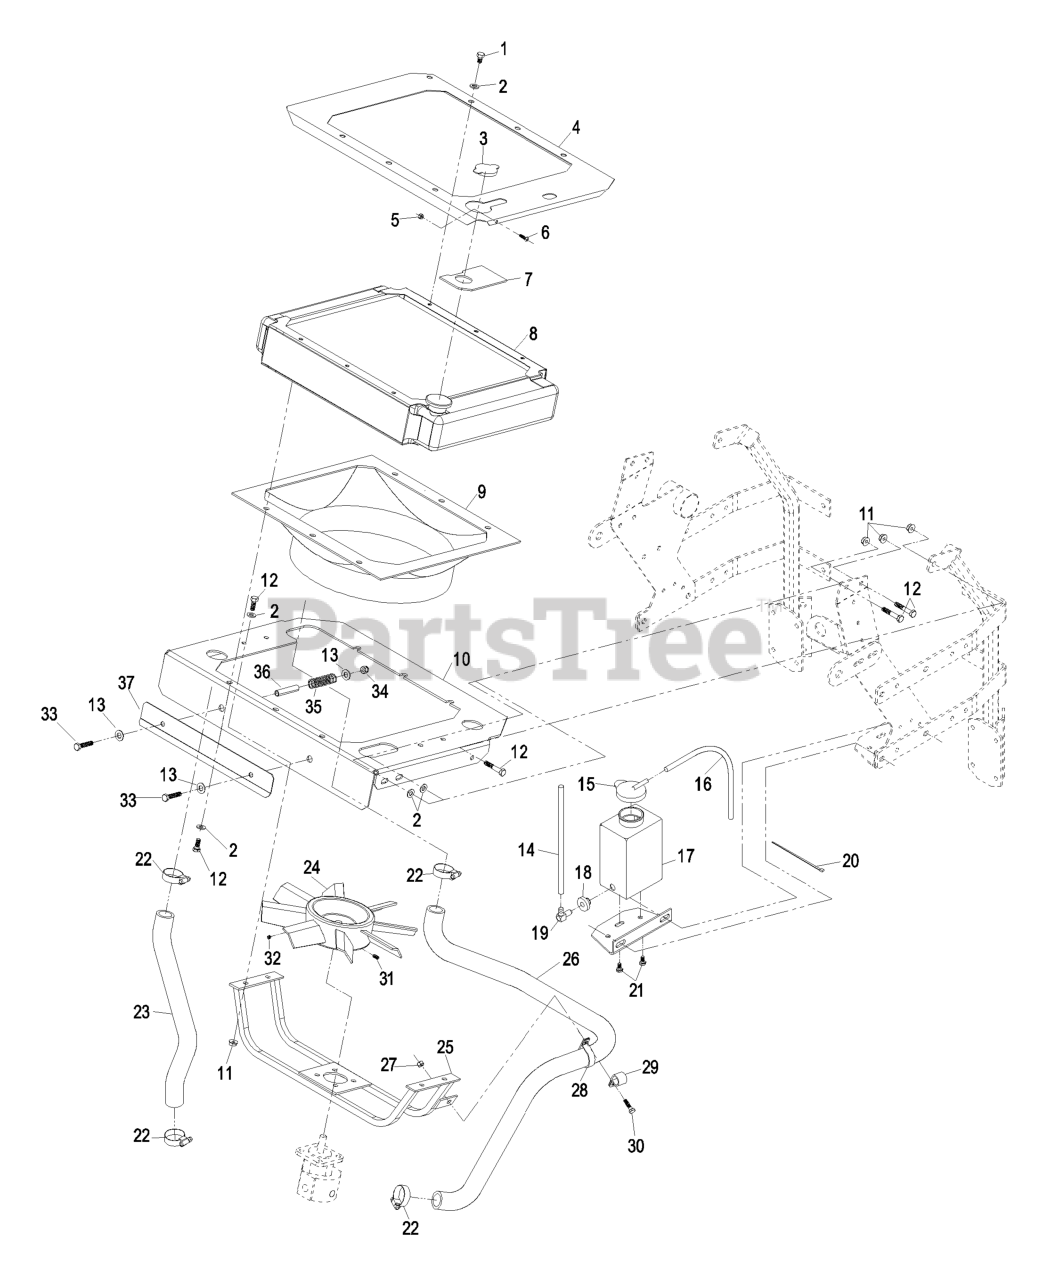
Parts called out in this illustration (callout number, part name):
1	SCREW-HH
2	WASHER-PLAIN
3	CAP-RADIATOR
4	ASM,RAD. TOP PLATE W/DECA
5	NUT-LOCK, NI
6	SCREW-HEAD, TRUSS
7	SHIELD-FILL NECK, RADIATO
9	SHROUD-COOLING, ENGINE
12	SCREW-HH
13	WASHER-FLAT
15	CAP-TANK, OVERFLOW
17	TANK-OVERFLOW
20	TIE-CABLE
21	SCREW-HH
23	HOSE-OUTLET, ENGINE
24	FAN
25	MOUNT-MOTOR, FAN
26	HOSE-INLET, ENGINE
27	NUT-LOCK, NI
28	CLIP-LOOM
29	CLIP-LOOM
30	SCREW-HH
31	SCREW-SET
32	Setscrew,1/4-20 X 1/4
33	SCREW-HH
34	NUT-LOCK, NI
35	SPRING-INDICATOR, REVERSE
37	BRACKET-DEFLECTOR, AIR
